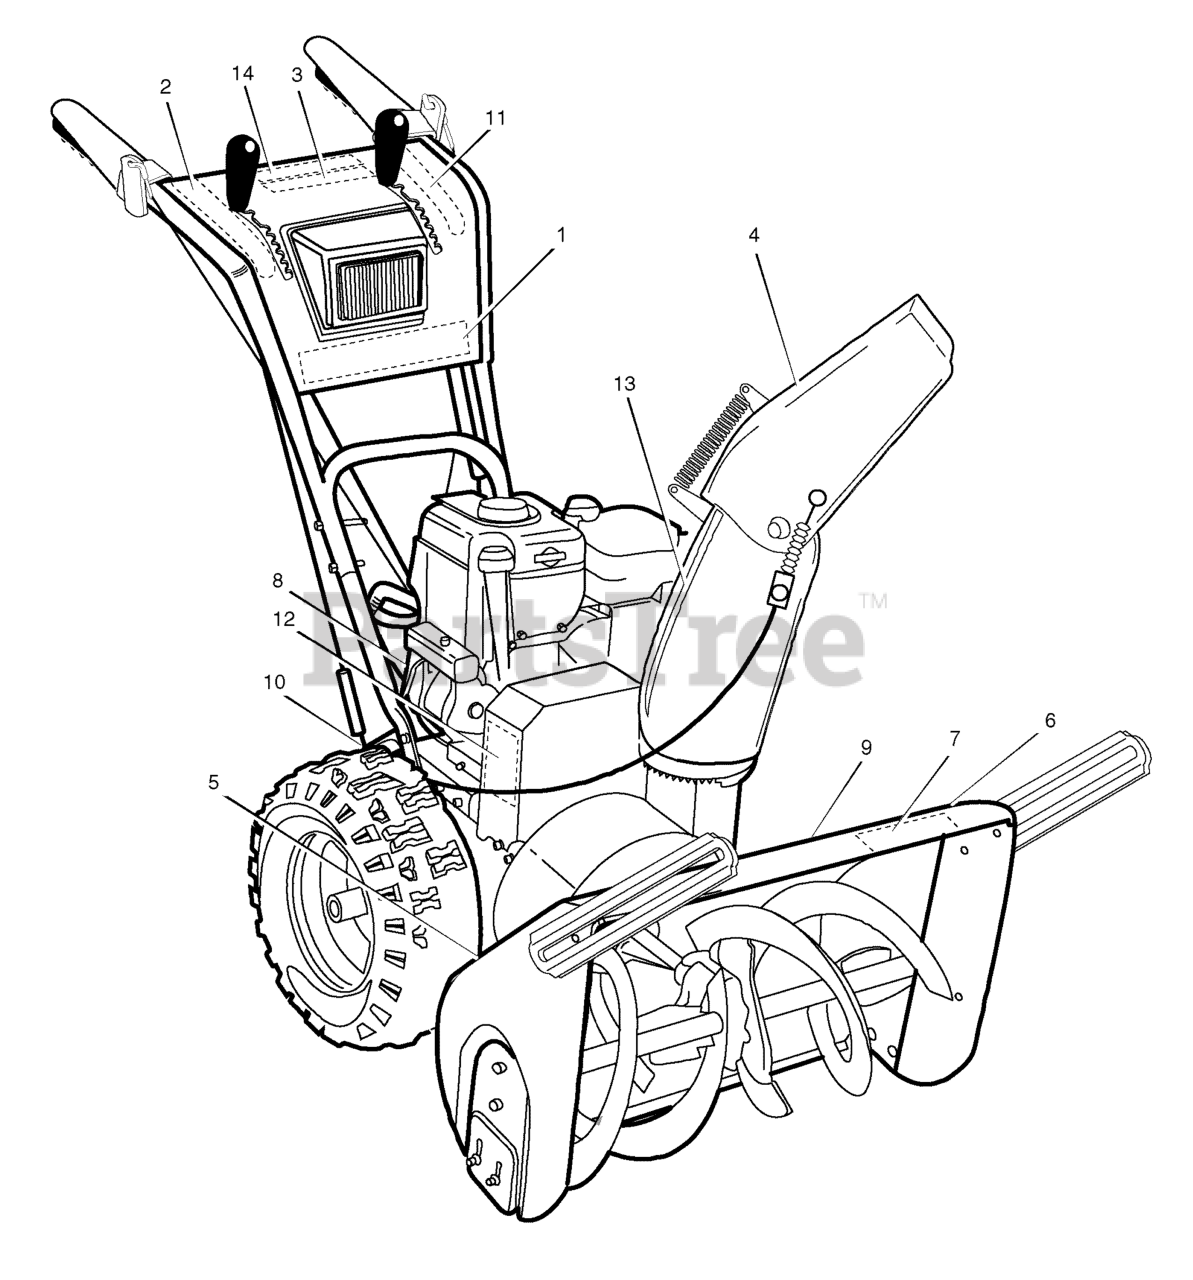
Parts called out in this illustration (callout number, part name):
1	DECAL, PANEL, BRUTE
2	DECAL, SPEED PANEL FR/EN
3	DECAL, TRACTION, AUGER DRIVE FR/EN
4	DECAL, DANGER THROWN OBJECTS FR/EN
5	DECAL, ISO AUGER FR/EN
6	DECAL, FACE HEAD PHONES
7	DECAL, BRUTE 1150/27 TOP AUGER
8	DECAL, OVER ADJUST OF DISC
9	DECAL, CLEAN-CLEAR BRUSH FR/EN
10	DECAL, ID PLATE
11	DECAL, REMOTE CHUTE P4 FR/EN
12	DECAL, BELT STRETCH
13	DECAL, DANGER CHUTE FR/EN
14	DECAL, SINGLE HAND CONTROL
